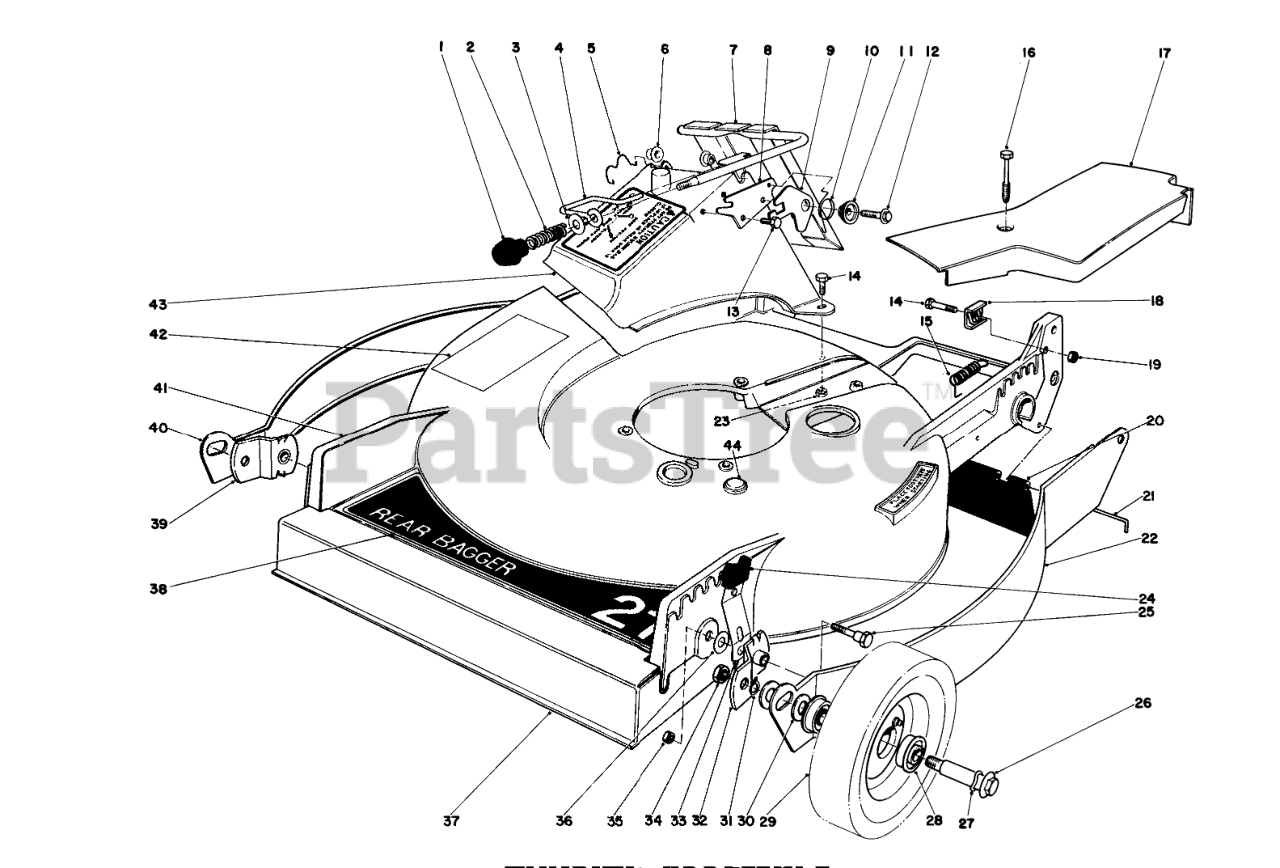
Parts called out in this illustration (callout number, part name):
2	COMPRESSION SPRING
3	WASHER
4	DOOR LATCH
5	DOOR RETAINER
6	BUSHING-NYLON
7	DOOR & HANDLE WA
8	DOOR LATCH PLATE
9	SAFETY LATCH
10	TORSION SPRING
11	Latch Spacer
12	Screw
13	SCREW-HWH
14	SCREW-HH
15	IDLER SPRING
16	SCREW-HHFTF
17	Belt Cover
18	CLAMP-CABLE
19	NUT-JAM
20	SHIELD - TRAILING
21	Rod Shield
22	LEFT SHIELD
23	NUT-LOCK, NI
24	KNOB-ARM
25	PIVOT SCREW
26	WHEEL BOLT
27	SPRING WASHER
28	BEARING-BALL
29	Wheel and Tire Assembly (Incl. Ref. #28)
30	WASHER
31	Grip Ring
32	PIVOT ARM ASM A
33	SPRING ARM ASM (R&S)
34	Nut
35	Nut
36	WASHER-PIVOT
37	FRONT SHIELD
38	Decal-Deck
39	PIVOT ARM ASM B
40	Right Shield
41	Housing
42	Decal-Caution
43	DISCHARGE CHUTE B
